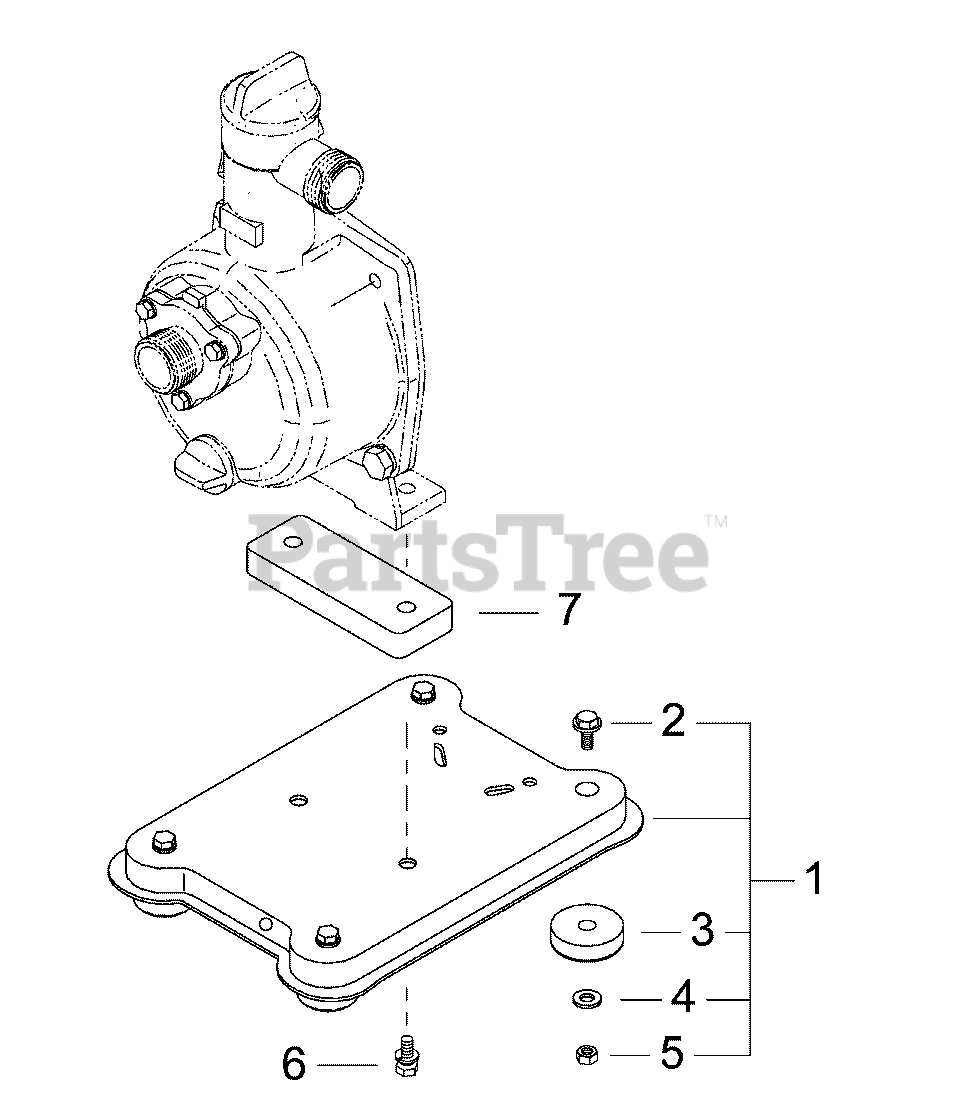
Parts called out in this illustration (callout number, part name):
1	BASE ASSY, PUMP
2	BOLT M6×16
3	CUSHION
4	WASHER Ø19
6	BOLT M8×25
7	SPACER 9 MM THICK
